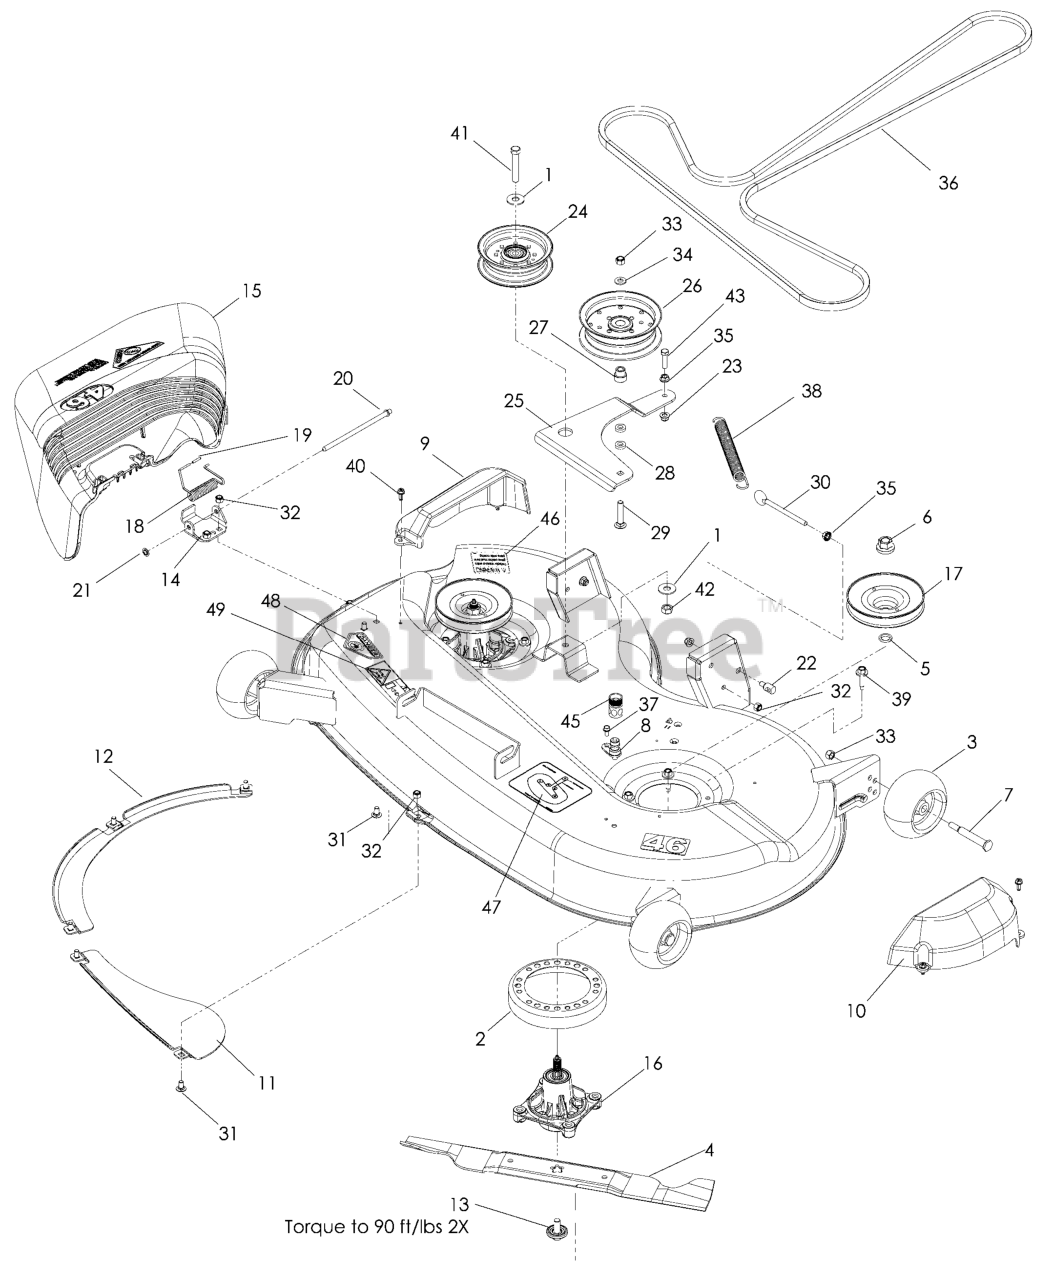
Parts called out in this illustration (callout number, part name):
1	WASHER 7/16 FLAT ZD
2	STRIPPER-ROUND-UNIVERSAL
3	GAUGE WHEEL
4	BLADE, 46" HI-LIFT
5	WASHER-SPACER
6	LOCKNUT - 9/16
7	SHOULDER BOLT 1/2X2-5/8 ZD SPE
8	PORT.WASHOUT
9	COVER.MANDREL.RH.46"
10	COVER.MANDREL.LH.46"
11	BAFFLE CENTER FRONT
12	BAFFLE FRONT RH
13	BOLT.WASHER.ASM.7/16-2
14	BRKT.DEFLECTOR.38"2005+
15	SHIELD.DEFLECTOR.MOWER.46"BLAC
16	CUTTER HOUSING
17	RP.PULLEY, DECK
18	TORSION SPRING
19	CAP-SLEEVE
20	ROD, HINGE
21	PUSH NUT
22	STUD.FASTNER.W/ANTI-ROTATE
23	5/16-18 NYLOC FLANGE NUT
24	PULLEY.IDLER.MWR.STATI.LH
25	ARM, IDLER, BLK
26	PULLEY, IDLER
27	IDLER BUSHING
28	WASHER 3/8 X 3/4 X .187 TK
29	RHSNB 3/8C X 2
30	EYE BOLT 5/16 X 3.50
31	CARRIAGE BOLT 5/16C X 5/8"
32	NUT 5/16 NYLOC
33	NUT 3/8-16 NYLOC
34	WASHER 3/8 SAE FLAT
35	NUT 5/16C WHIZ
37	BOLT 1/4-20 X 1/2 HWST
38	SPRING, DECK BELT
39	WASHER HEAD SCREW
40	SCREW- 1/4-20 X 5/8
41	BOLT 7/16-14 X 2-1/2 GR 5 ZD
42	7/16-14 HEX NUT W/NYL RING ZD
43	HCS 5/16C X 1 1/4
44	DECK W/DECALS - LSZ46
45	COUPLING.QUICK CONNECT
46	DECAL, CAUTION
47	DECAL, BELT ROUTING
48	DECAL, CPSC
49	DECAL, EURO SEVERING
